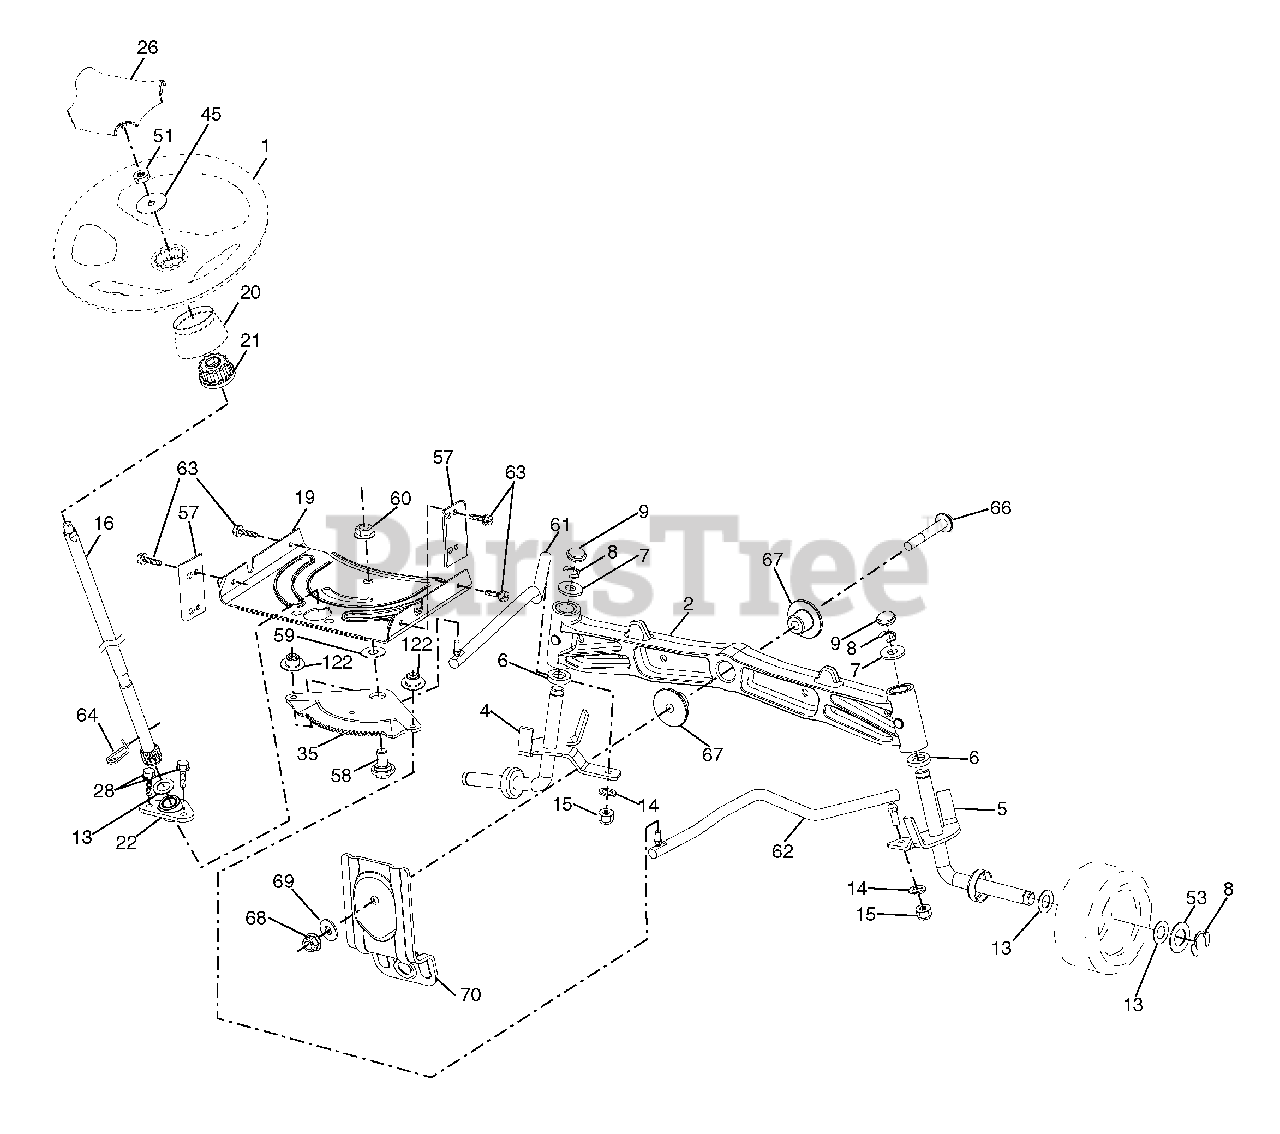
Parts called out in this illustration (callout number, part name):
1	Wheel, Steering
2	Axle Asm., Front
4	Spindle Asm., LH
5	Spindle Asm., RH
6	Bearing, Race Thrust Harden
7	Washer 25/32 x 1-5/8 x 16 Ga.
8	Ring, Clip #T5304-75
9	Cap, Spindle
13	Washer 25/32 x 1-1/4 x 16 Ga.
14	Washer, Lock Hvy Hlcl Spr 3/8
15	Nut, Crown Lock 3/8-24 unf
16	Shaft Steering
19	Plate Steering
20	Boot, Steering
21	Adapter, Wheel Steering
22	Steering Support Lower
26	Insert, Wheel Steering
28	Screw 3/8-16 x 3/4
35	Gear, Sector Plate
45	Washer 9/16 ID x 2-3/8 x 12 Ga.
51	Nut Hex Jam Toplock 1/2-20 unf
53	Washer Hardened .793 x 1.637 x .060
57	Bracket Upstop
58	Bolt Shoulder Sector Pivot CFM
59	Washer Thrust Sector Steering
60	Nut Flange Lock 5/8-11
61	Draglink, LH
62	Draglink, RH
63	Screw 5/16-18 x 3/4
64	Retainer Clip Spring Steering
66	Bolt Hex Fghd 7/16-14 x 3 Serr
67	Bushing PM Front Axle
68	Nut Lock Flange 7/16-14 Gr. 5
69	Washer 1.5 x .505 x .118
70	Bracket Deck Susp. Front
122	Cap Gear Sector
